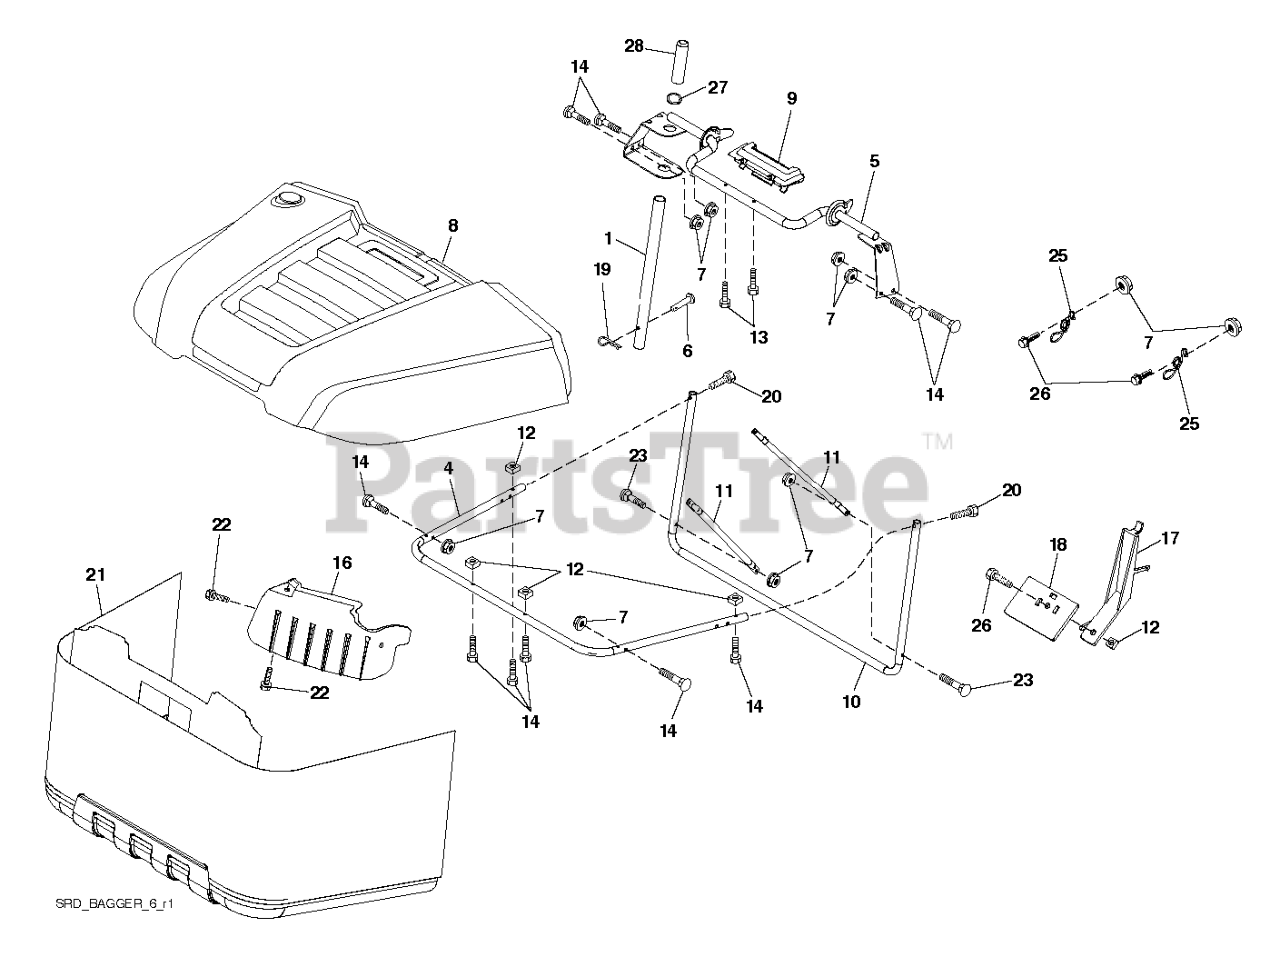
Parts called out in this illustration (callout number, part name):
1	TUBE.HANDLE.BAGGER.CRD/SRD.BLA
4	SUBASM.TOP.TUBE.TEX.CRD
5	FRAME.ASM.TOP.BAGGER.SRD
6	RIVET,DRILLED
7	NUT T
8	BAGGER.TOP.SUB.ASSEM.SRD
9	INSERT.HANDLE.BAGGER.(2 2)
10	FRAME.FRONT.SRD.BAGGER
11	TUBING.BRACE.BAGGER.SRD.BLACK
12	NUT.SQUARE.1/4
13	SCREW.1/4X1.150.HXWSH
14	BOLT.SHOULDER.HX.WSH.1/4X1.150
16	DEFLECTOR.BAGGER.SRD
17	LEVER.BAGGER.FULL.SRD.BLACK
18	PADDLE.BAGGER.FULL.SRD.BLACK
19	PIN.COTTER.5/16.BOW TI
20	SCREW.HEXCAP.1/4-20X1.375(2 2)
21	BAG.ASM.BAGGER.SRD.HUSQVA.GREY
22	SCREW.HI-LO.CONSOLE
25	SPRING.LATCH.BAGGER.SRD
26	SCREW HEX CRT
27	RB GROMMET.RUBBER.SRD
28	GRIP.HANDLE.BLACK
